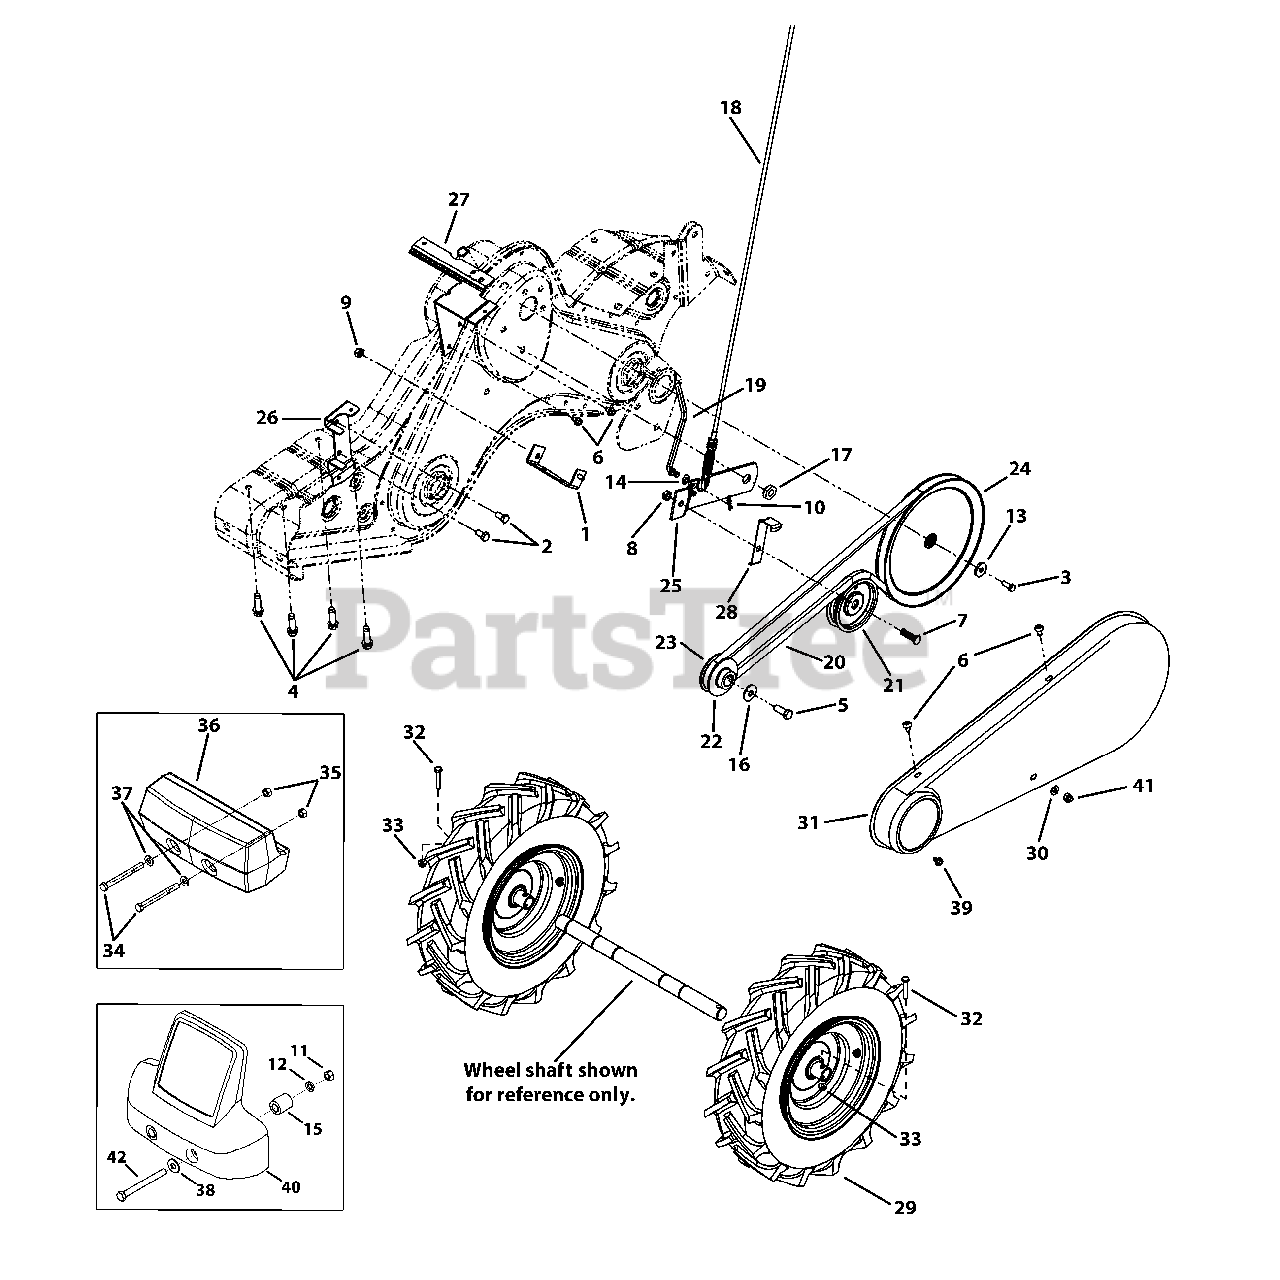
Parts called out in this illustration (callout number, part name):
1	Belt Cover Bracket Assembly
2	Hex Bolt, 5/16-24 x .625
3	Hex Bolt, 1/4-28 x .75"
4	Hex Washer Screw, 3/8-16 x 1.50"
5	Hex Bolt, 3/8-24 x 1.0
6	Hex Washer Screw
7	Hex Cap Screw, 3/8-16 x 1.25
8	Lock Jam Nut, 3/8-16
9	Flangelock Nut, 5/16-18
10	Internal Cotter Pin
11	Hex Nut, 1/2-20
12	Washer, Lock, 1/2
13	Flat Washer, .25 ID x .93 OD
14	Spring Washer, .317 ID x .625 OD
15	Hub, .636 ID x 1.00 OD x .94
16	Bell Washer, .396 ID x 1.14 OD
17	Shoulder Nut, 7/16-20
18	Clutch Cable
19	Idler Pulley Rod
21	Flat Idler w/ Flange, 3.75 OD
22	Outer Engine Pulley Half
23	Inner Engine Pulley Half
24	Input Pulley
25	Idler Bracket
26	Belt Keeper Bracket
27	Shift Cover Bracket
28	Idler Belt Keeper
29	Wheel Assembly, 16.0 x 4.6 x 8
30	Flat Washer, .271 ID x .630 OD
31	Belt Cover
32	Hex Head Screw, 1/4-20
33	Flange Lock Nut, 1/4-20
34	Hex Bolt, 1/2-13 x 5.0
35	Flange Lock Nut, 1/2-13
36	Counterweight, 40 lbs.
37	Flat Washer
38	Washer, Flat, 1/2 x 1.25 x .100
39	Hex Screw, 1/4-20 x .375
40	Counterweight
42	Hex Head Screw, 1/2-13 x 5.50
